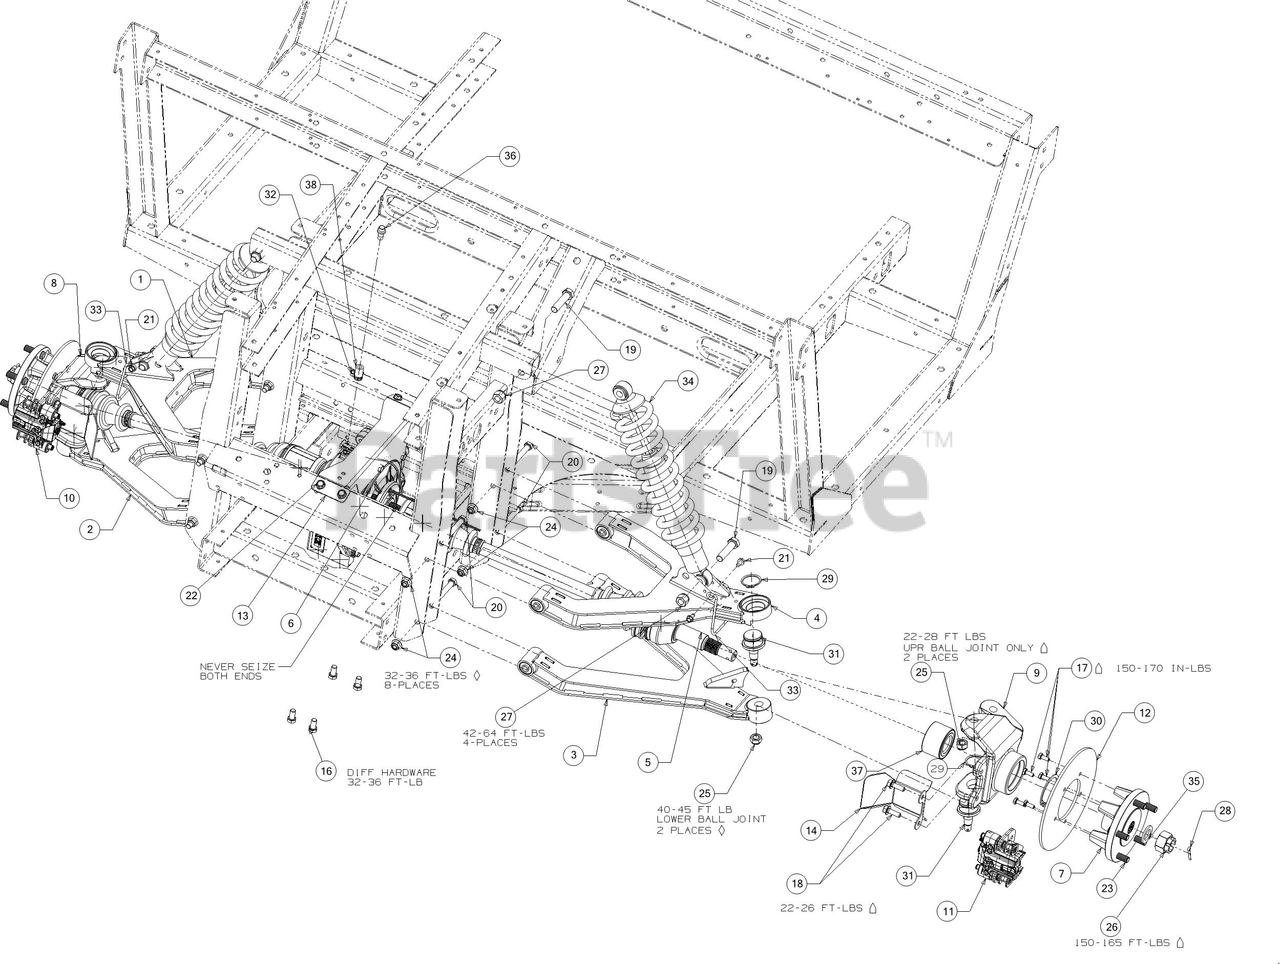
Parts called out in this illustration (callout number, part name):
1	UPPER CONTROL ASSEMBLY
2	LOWER CONTROL ASSEMBLY
3	LOWER CONTROL ASSEMBLY
4	UPPER CONTROL ASSEMBLY
5	CV JOINT AXLE ASSEMBLY
6	DIFF ASSEMBLY
7	WHEEL HUB ASSEMBLY
8	KNUCKLE HOUSING (FRONT/RH)
9	KNUCKLE HOUSING (FRONT/LH)
10	FRONT BRAKE CALIPER ASSEMBLY (RH)
11	FRONT BRAKE CALIPER ASSEMBLY (LH)
12	BRAKE DISC 8.00 x .188
13	FRONT DIFFERENTIAL MOUNT
14	STEERING SHIELD BRACKET (LH)
16	HEX SCREW 3/8-16 x .75
17	SCREW 1/4-20 x .62 SPEC GR5
18	SCREW M8 x 1.25 x 25MM GR8.8
19	SCREW 1/2-13 x 2 GR5
20	SCREW 3/8-16 x 3 GR8
21	SCREW 1/4-20 X.500
22	SCREW 5/16-18 x .500
23	STUD 7/16-14 x 1.6
26	SLOTTED NUT22X1.5
27	HEX LOCK NUT NYLON
28	COTTER PIN-5/32 DIA
29	RETAINING RING
30	RETAINING RING
31	BALL JOINT
32	HOSE CLAMP
33	BRAKE LINE WIRE
34	FRONT SHOCK ABSORBER
35	THRUST WASHER
37	DOUBLE ROW BEARING
38	FUEL HOSE LOW PERMEATION
